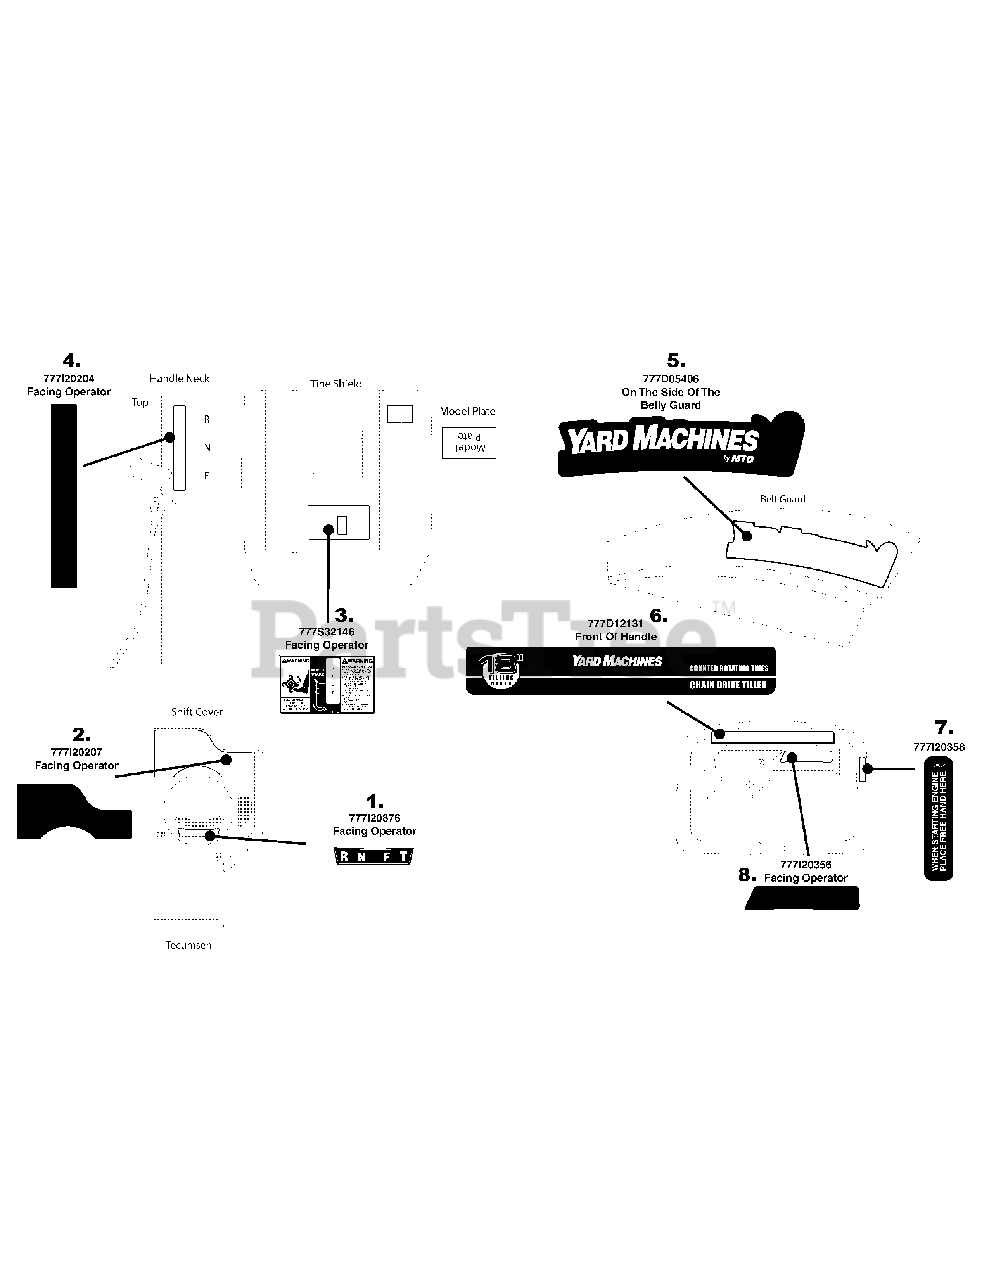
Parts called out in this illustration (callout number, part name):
1	LABEL-INDICATOR TI
2	LBL:F N R TINE DIR
3	LABEL-TINE SHIELD
4	LABEL F-N-R
5	LABEL-BELT GUARD
6	LABEL-TILLER HANDLE/FRONT CRT
7	LABEL-PLACE HAND HERE
